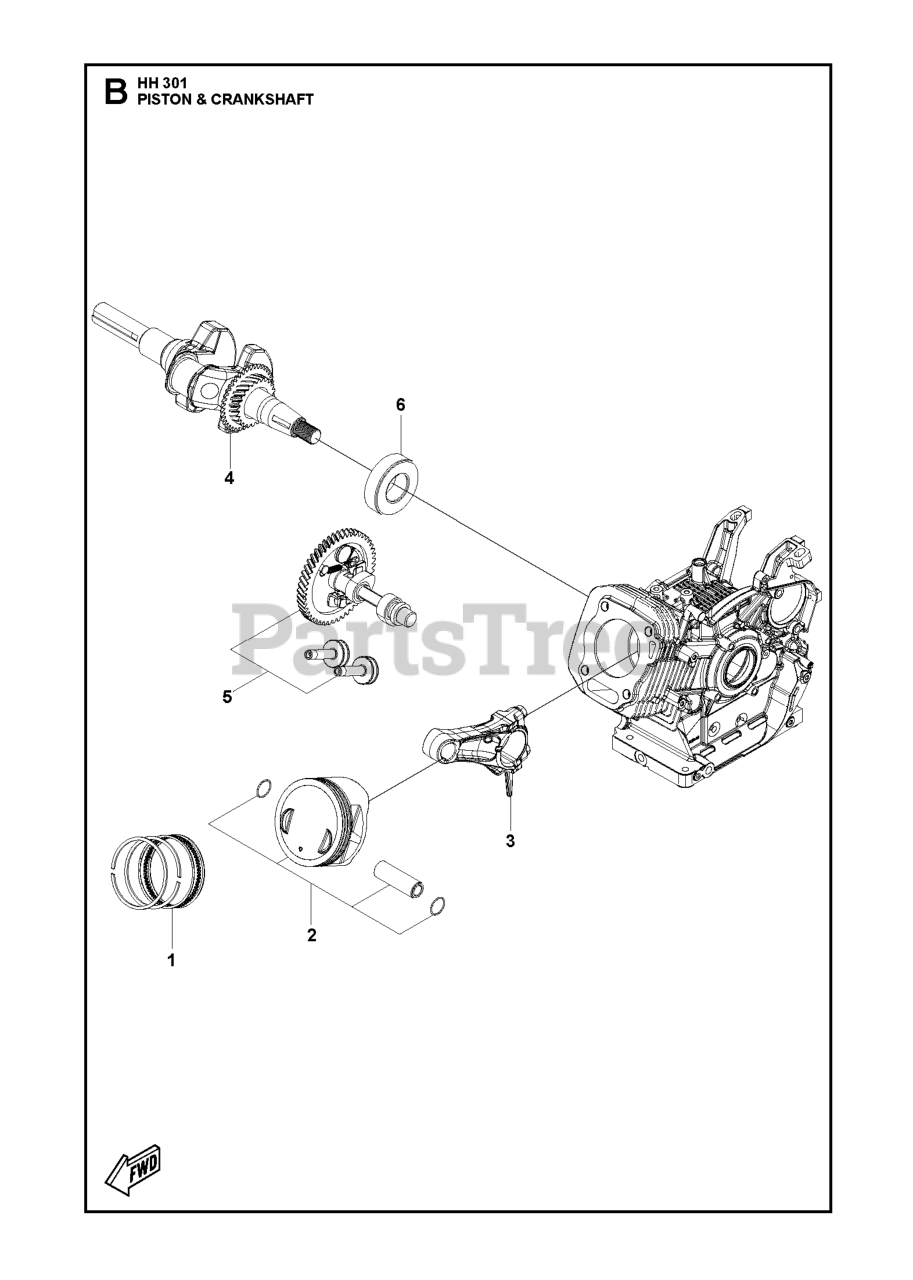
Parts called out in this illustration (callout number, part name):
1	PISTON RING SET
2	PISTON ASSY
3	CONNECTING ROD
4	CRANKSHAFT
5	CAMSHAFT KIT
6	BALL BEARING
